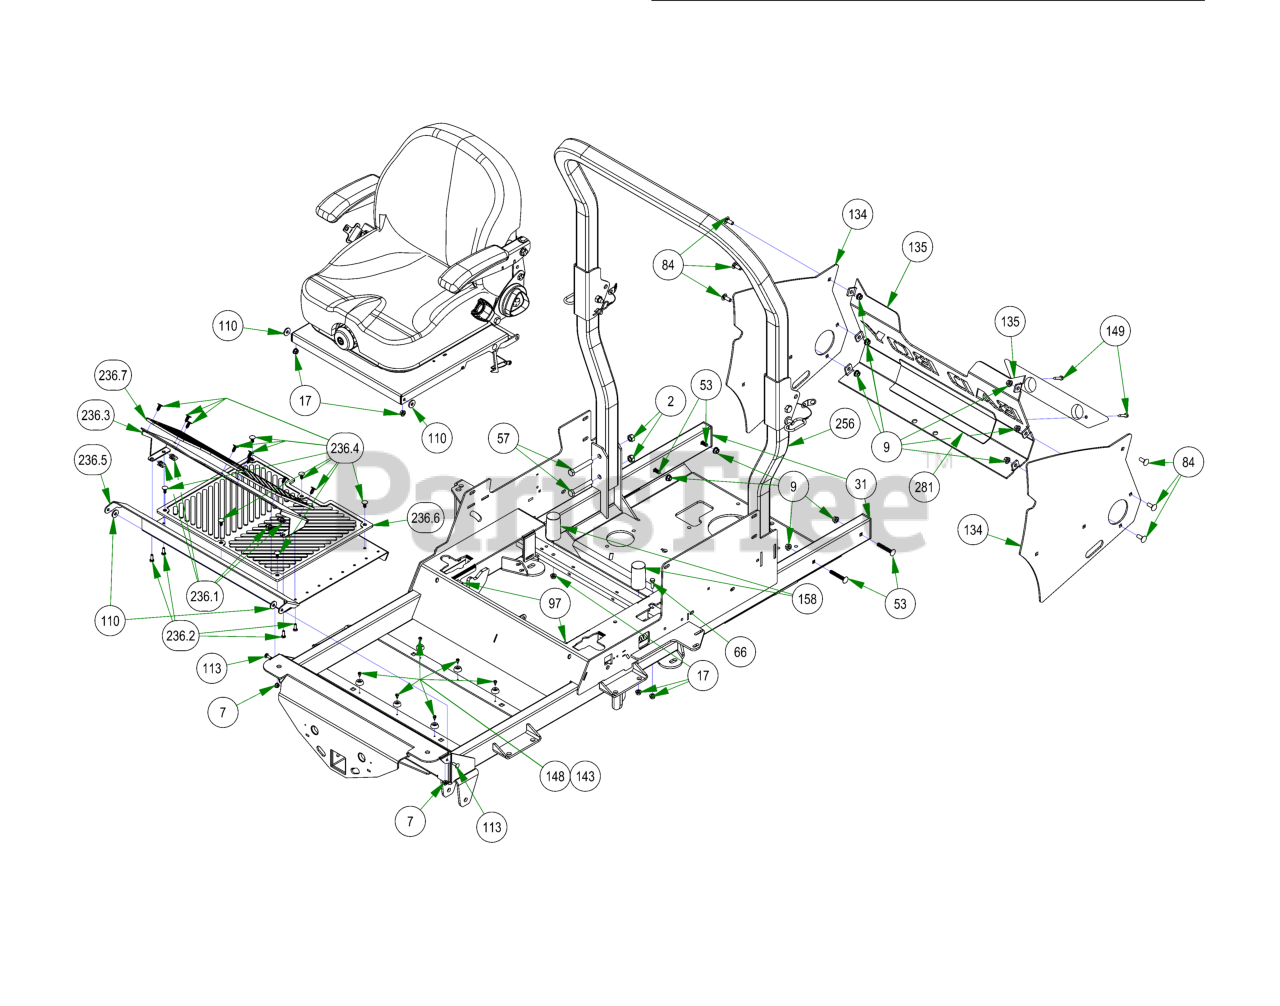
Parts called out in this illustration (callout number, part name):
2	1/2-13 HEX 2-WAY REVERSIBLE CENTER LOCKNUT Grade B ZINC
7	1/4-20 NYL INSERT FLANGE LOCKNUT ZINC
9	3/8-16 NYLON INSERT FLANGE LOCKNUT (GR.F) ZINC
17	5/16-18 NYLON INSERT FLANGE LOCKNUT ZINC
21	5/16-18 HEX SERRATED FLANGE NUT HARD/ZINC
31	1 1/2 x 3 Frame Plug
49	M6-1.0 X 16MM DIN 933 HEX TAP BOLT (CL 8.8) ZINC
53	3/8" x 2 1/2" Carriage Bolt
57	1/2-13 X 3-1/4 HEX CAP SCREW (GR.5) ZINC
66	5/16-18 X 1 HEX CAP SCREW (GR.5) ZINC
84	3/8-16 X 1 CARRIAGE BOLT (GR.5) ZINC
97	5/16-18 X 1 CARRIAGE BOLT (GR.8) ZINC
110	.360 ID X .983 OD X .120 THICK FLAT WASHER NYLON
113	1/4-20 X 3/4 CARRIAGE BOLT (GR.5) ZINC
133	R-SERIES SEAT PLATE ASSEMBLY
134	2019 Rouge Rear Cover Side Plate
135	2019 Vertical Rear Cover Tailgate - Black
143	Button Bumper
146	2017 XP Bumper
148	10-16 X 1/2 PAN PHIL TEK/3 CLIMASEAL OR ACF-SILVER COATED
149	1/4-14 X 1-1/2 HEX WASHER UNSLOT TEK/3 ZINC
158	2019 Bad Boy X Cylindrical Seat Mount
218	2019 Outlaw EPA Cannister Assembly
230	2021 Rogue Suspension Frame Painted
231	2022 Suspension Seat w/Seatbelt
236	R-Series Floorboard Assembly
236.1	1/4-20 Cage Nut
236.2	1/4-20 X 3/4 HEX CAP SCREW (GR.5) ZINC
236.3	OUTLAW ADJUSTABLE FOOT PLATE-ORANGE
236.4	Ratchet Fastener
236.5	2019 Outlaw Floorboard
236.6	MAT (FLOOR)
236.7	MAT (FOOT PLATE)
256	2019 2X2 Folding ROPS
281	Heat Shield (Fiberglass Adhesive)
